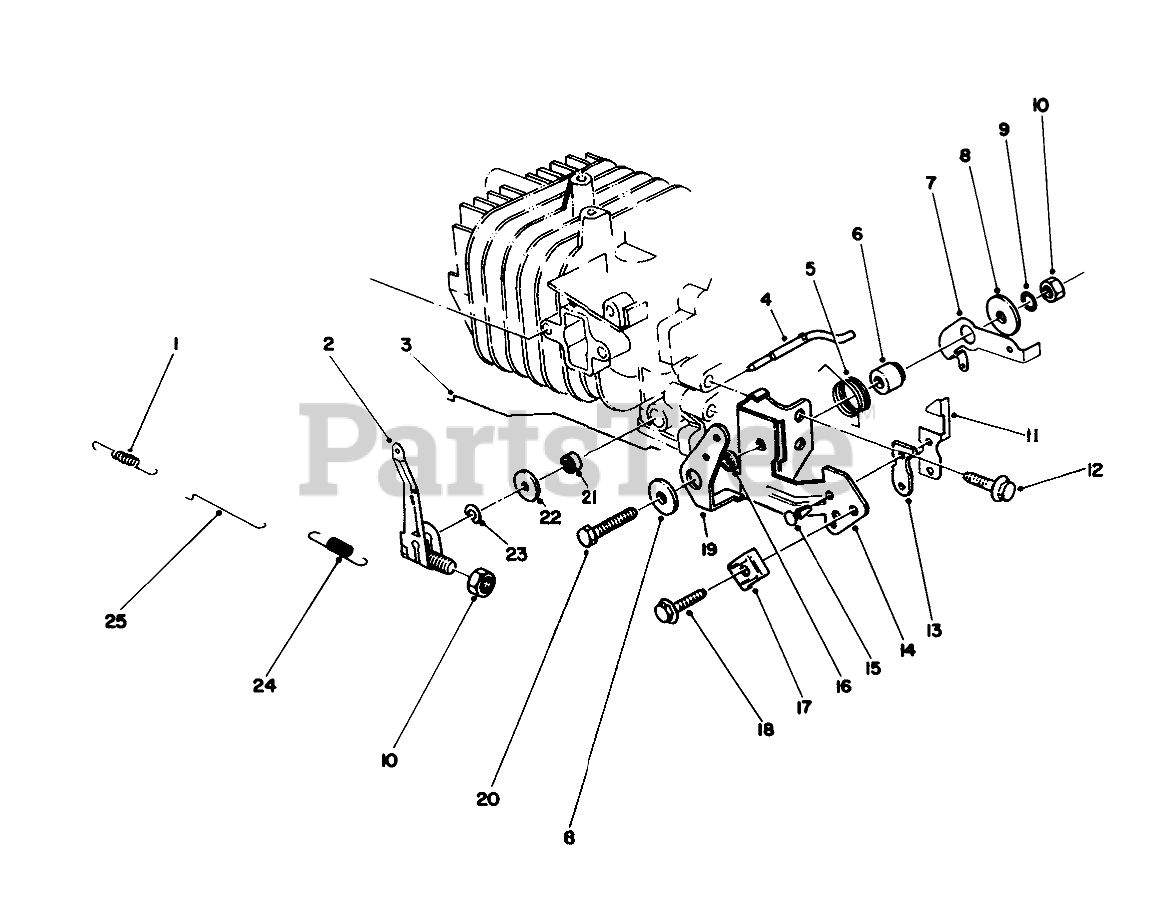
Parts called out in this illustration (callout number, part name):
1	SPRING
2	ARM-GOVERNOR
3	ROD-CHOKE
4	Shaft-Govemor
5	SPRING-CHOKE LEVER
6	Gov Lever Spacer
7	LEVER-SPRING, GOVERNOR
8	WASHER
9	LOCKWASHER
11	TERMINAL-KILL SWITCH
13	INSULATOR-KILL SWITCH
14	BRACKET-THROTTLE, CONTROL
15	KILL SWITCH RIVET
16	SPACER-CHOKE LEVER
17	CLAMP
19	LEVER-CONTROL, CHOKE
21	SEAL-OIL
22	WASHER
23	E-RING
24	SPRING-GOVERNOR
25	ROD-CARBURETOR
